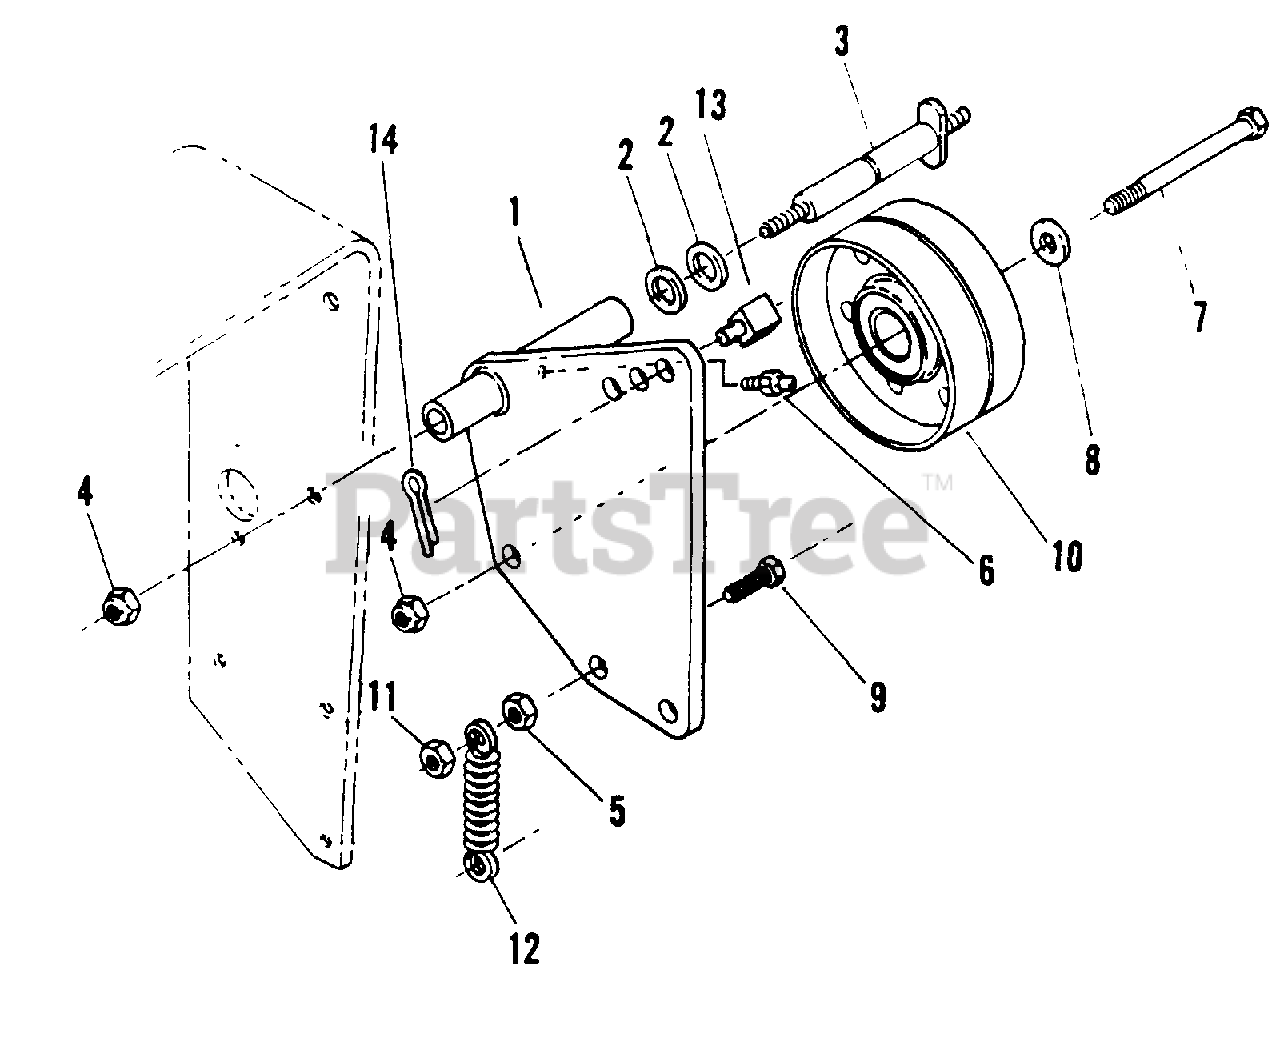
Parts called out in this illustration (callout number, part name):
1	ARM, Traction R.H.
2	MACHINE BUSHING, 5/8"
3	STUD, Fender Mount
4	NUT, 3/8" C Nyloc
5	NUT, 5/16C Flange Lock
6	GREASE FITTING, 1/4" - 28 Str. Zerk
7	SCREW, 3/8" -16 x 2-1/4" Lg. Hex Cap
8	FLATWASHER, 3/8"
9	BOLT, 5/16 - 18 x 1-1/4" Hex
10	PULLEY, Idler 4.0
11	NUT, 5/16"
12	SPRING, Traction
13	SWIVEL, Traction Rod
14	PIN, 3/32 x 1' Cotter
